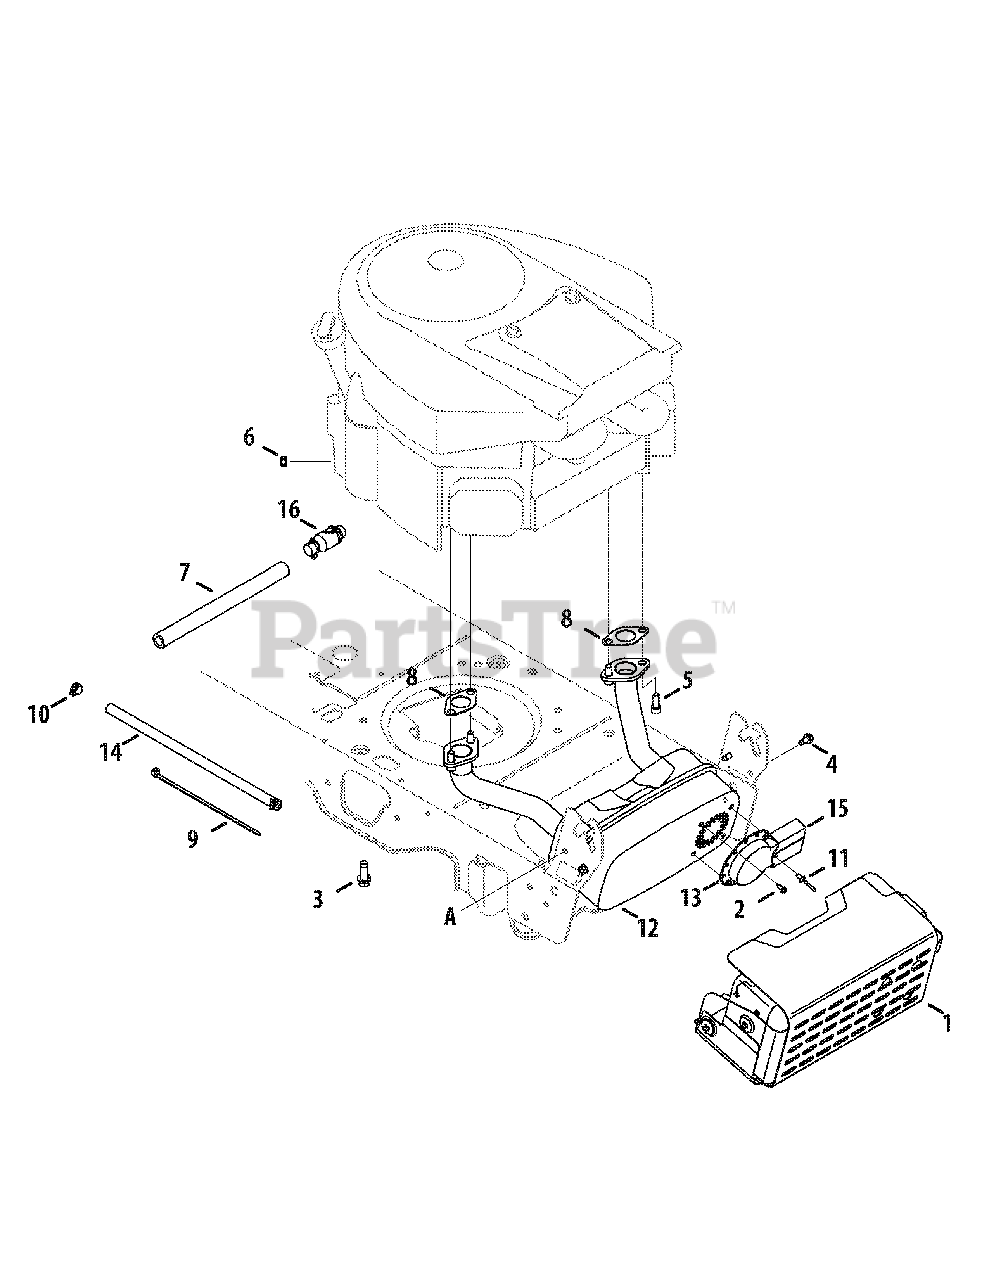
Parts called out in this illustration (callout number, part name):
1	Shield Ass’y, Muffler
2	Screw, Ab, #8-18, 0.500,
3	Screw, Self-tapping, 3/8-16, 1.000,
4	Screw, Self-tapping, 1/4-20, 0.500,
5	Screw, Socket Head, 5/16-18, .750
6	Nut, Sems, 1/4-20
7	Hose, Extension, Oil Drain
8	Gasket, Exhaust
9	Cable, Tie, 3/16 x .05 x 7.4
10	Clamp, Hose, .490 Dia.
11	Rivet, Pop, .188 Dia x .300
12	Muffler, Intek Twin
13	Deflector, Muffler
14	Hose, Fuel, Low Permeation, 1/4
15	Deflector, Muffler, Long
